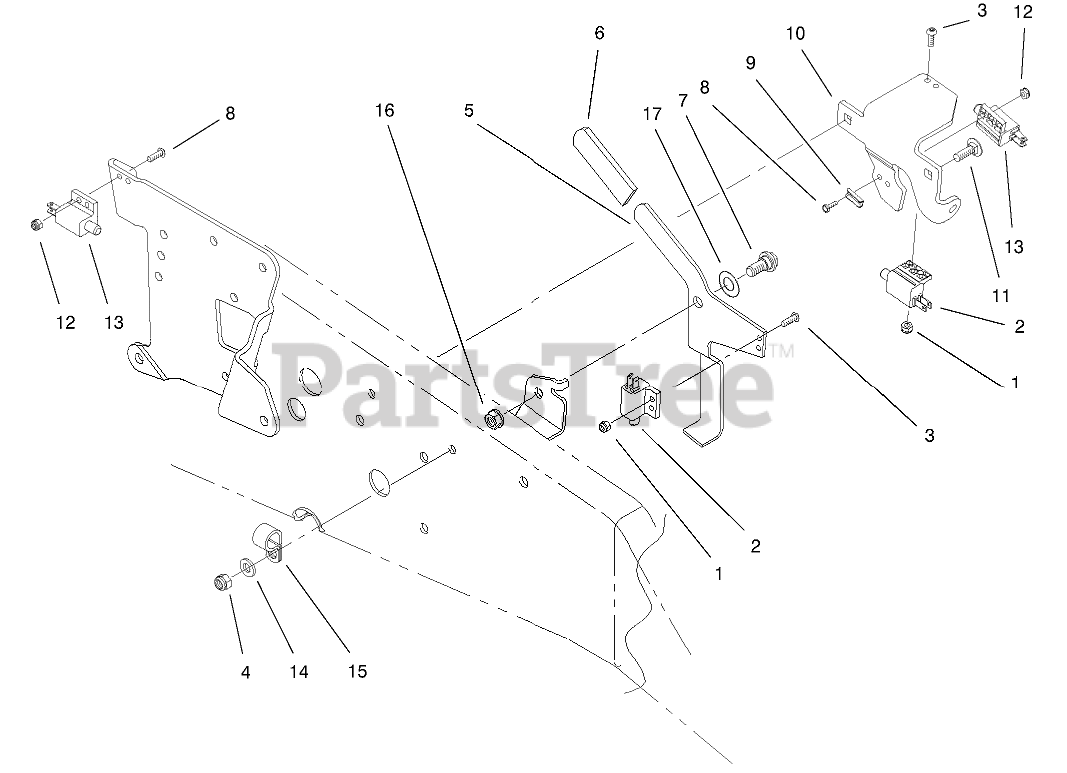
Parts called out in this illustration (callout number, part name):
1	NUT-LOCK, NI
2	SWITCH-POLE, SINGLE
3	SCREW-HSH
4	NUT-LOCK, NI
5	LATCH-BRAKE, PARKING
7	BOLT-SHOULDER
8	Screw
9	RETAINER-SCREW
10	BRACKET-SWITCH
11	SCREW-CARR
12	NUT-LOCK
13	SWITCH-POLE, SINGLE
14	WASHER-PLAIN
15	CLAMP - R
17	WASHER
